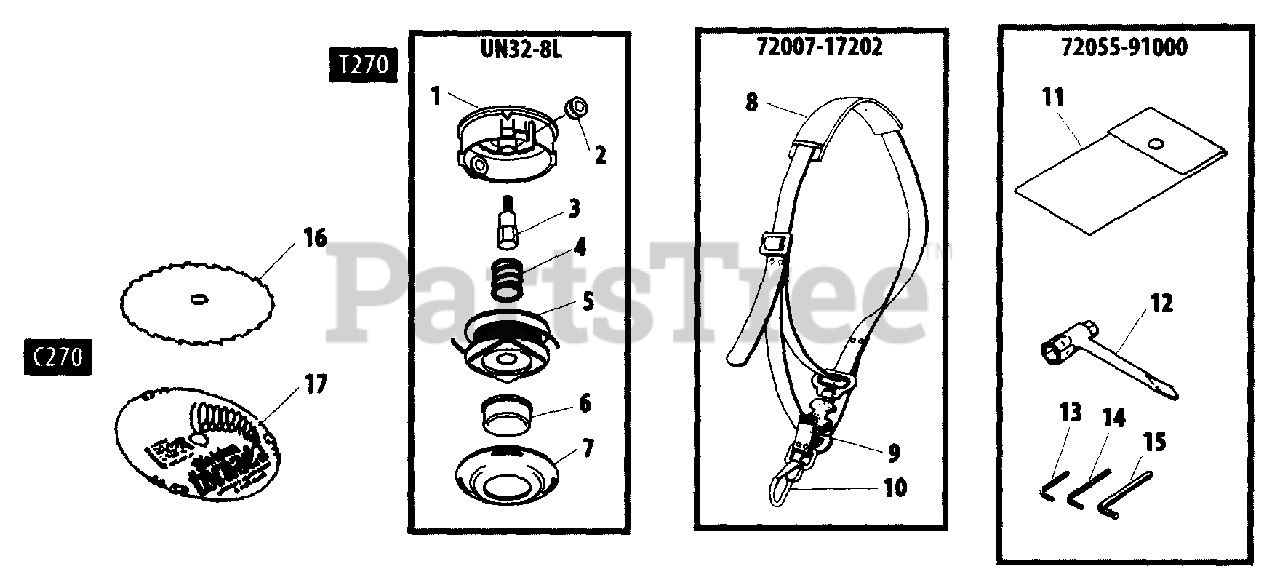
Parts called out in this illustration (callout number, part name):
3	SHAFT BOLT
8	PAD
9	CUSHION, HARNESS
10	HOOK
11	BAG, TOOL
12	T-WRENCH - 13X19mm
13	HEX KEY - 3mm
14	HEX KEY - 4mm
15	HEX KEY - 6mm
16	BLADE, 30 TOOTH - 25mm -- 8"
17	BLADE - 6 TOOTH -- 9" (22cm)
